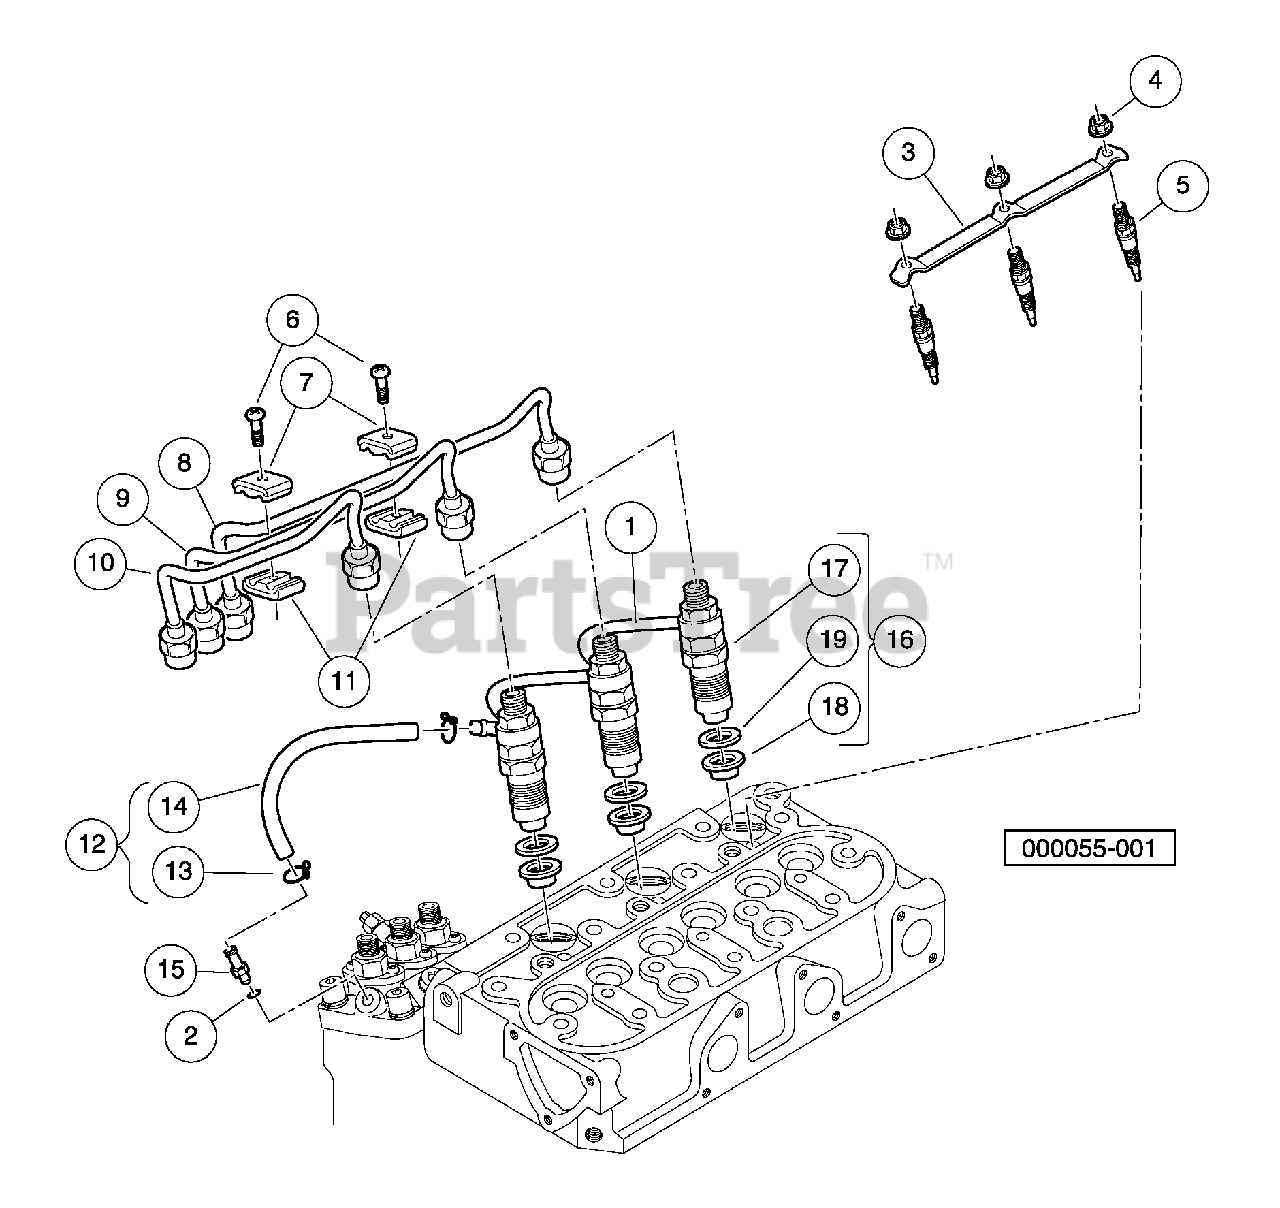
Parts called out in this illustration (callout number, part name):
1	Assy Pipe, D722 Fuel Over Flow
2	Gasket, 6 X 10
3	Cord, Glow Plug
4	Nut, Flange,m4
6	Screw, Washer
7	Clamp, Pipe, Top
8	Pipe, Injection, Left
9	Pipe, Injection, Right
10	Pipe, Injection, Middle
11	Clamp, Pipe, Bottom
12	Assy Pipe, Over Flow
13	Clip, Pipe, Return
14	Hose, Overflow
15	Screw, Air Bleeder
16	Kit, Holder, Nozzle
17	Assembly, Nozzle Holder
18	Seal, Heat.
19	Gasket, Nozzle
